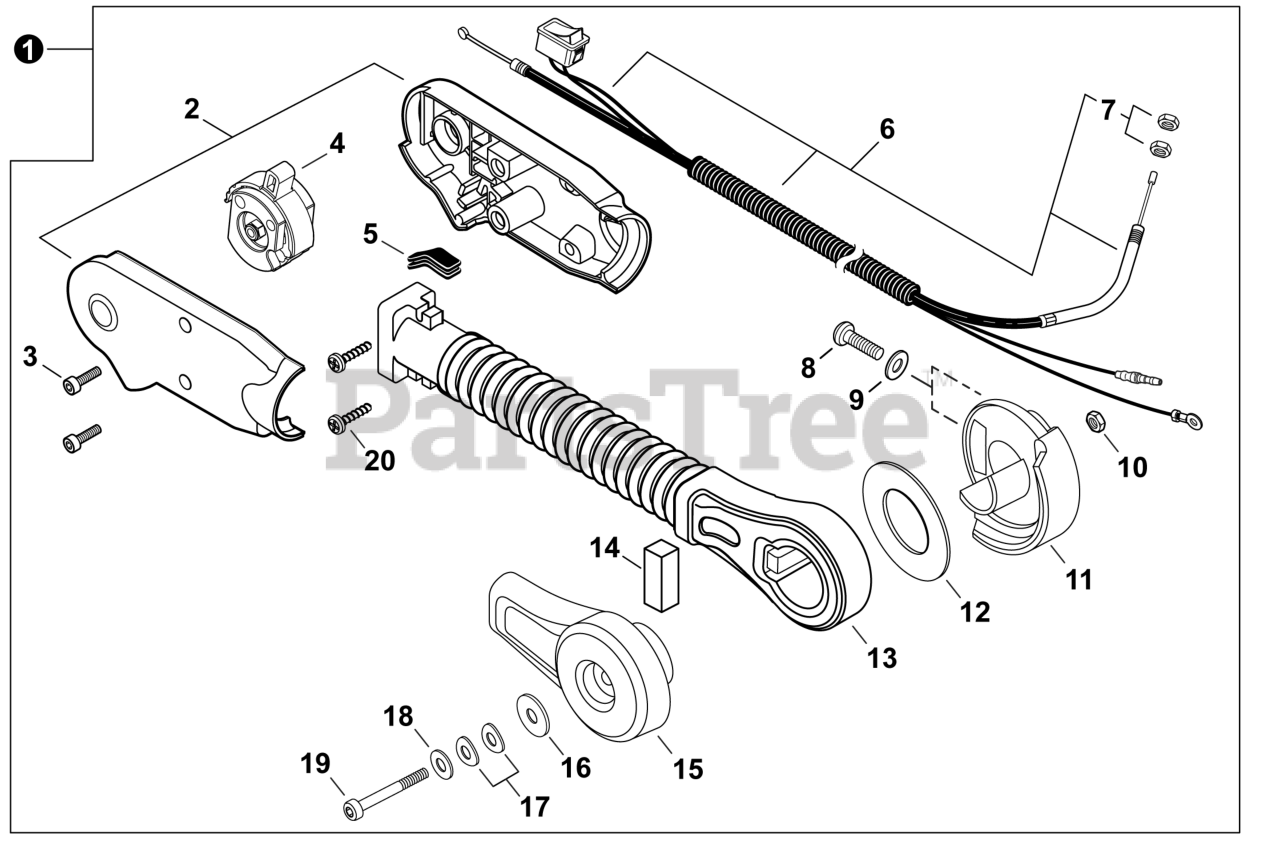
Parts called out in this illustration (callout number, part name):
1	THROTTLE CONTROL KIT - HIP MOUNT
2	GRIP SET, THROTTLE
3	BOLT, TORX 5x16
4	CONTROL, THROTTLE
5	GROMMET
6	CABLE ASSY, CONTROL
8	BOLT, TORX 5x20
9	WASHER 5.5x16x0.8
10	NUT, LOCK M6
11	BRACKET, ARM - INNER
12	WASHER 45
13	ARM, THROTTLE CONTROL
14	SEAL, DUST - FOAM
15	BRACKET, ARM - OUTER
16	WASHER 6.6x20x1.6
17	WASHER, FRICTION 6.6x14.3
18	WASHER 6.5x15.5x0.6
19	BOLT, TORX 6x75
